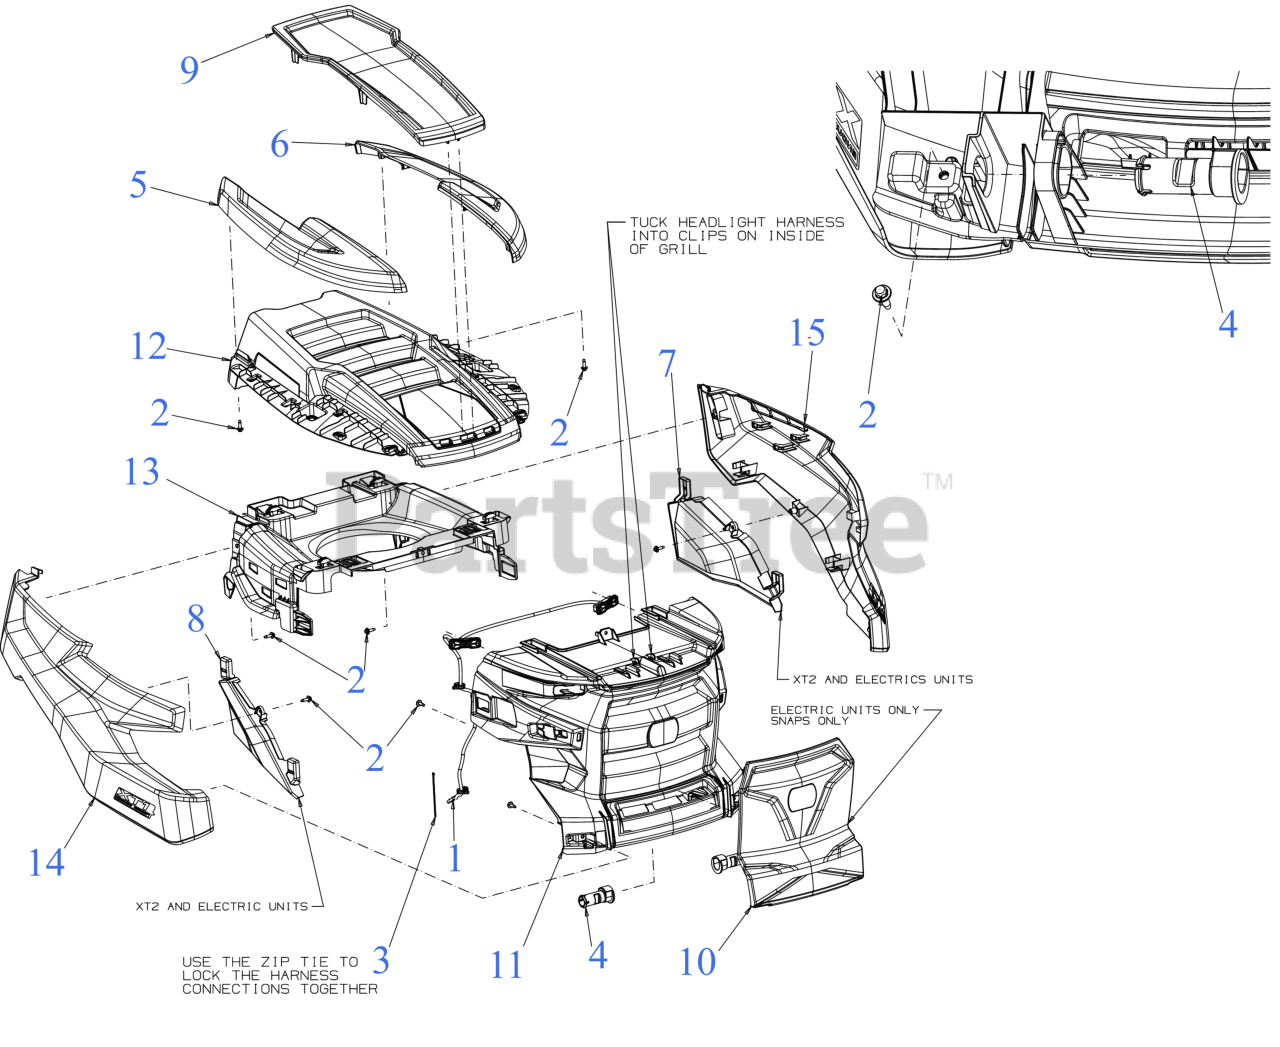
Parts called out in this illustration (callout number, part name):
1	HEADLIGHT HARNESS (W/LED)
2	SCREW 1/4-10 x .750
3	CABLE TIE
4	HOOD PIVOT PIN
5	HOOD (TOP) (RH)
6	HOOD (TOP) (LH)
7	PANEL (LOWER SIDE) (LH)
8	PANEL (LOWER SIDE) (RH)
9	HOOD PANEL (TOP) (T STYLE)
10	HOOD PANEL (FRONT) (T STYLE)
11	GRILL (T STYLE)
12	PANEL (TOP) (T STYLE)
13	HOOD PLENUM (T STYLE)
14	PANEL (UPPER) (RH) (T STYLE)
15	PANEL (UPPER) (LH) (T STYLE)
